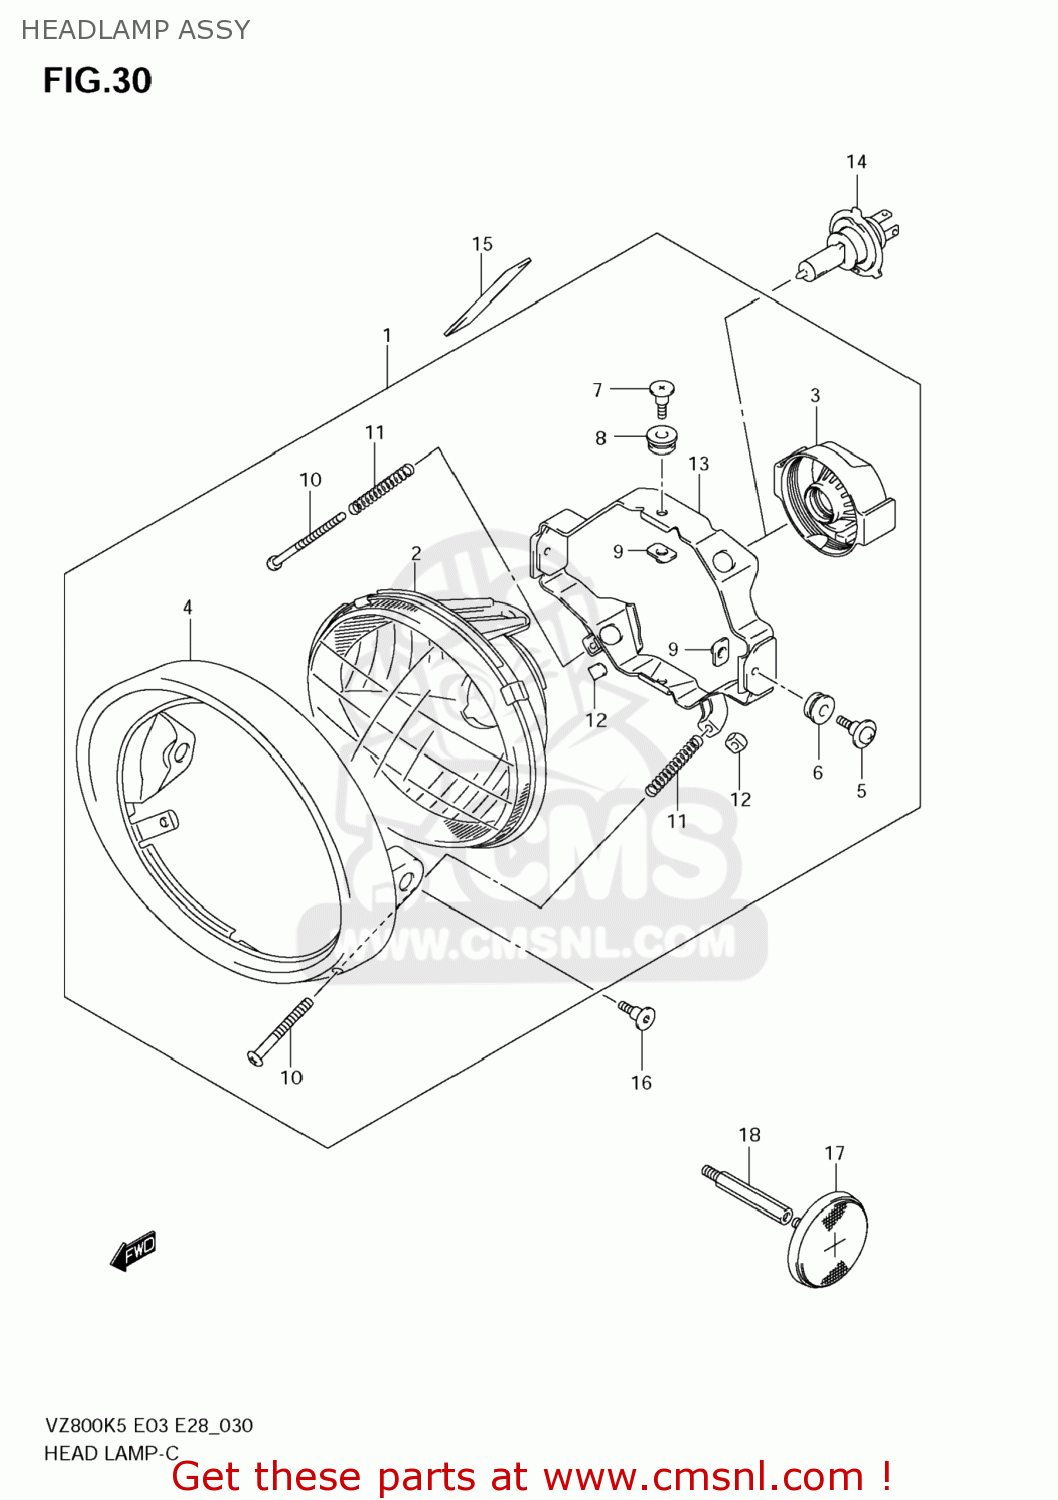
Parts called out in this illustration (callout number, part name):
1	HEADLAMP ASSY
2	UNIT
3	COVER
4	RIM
5	SCREW,MOUNTING
6	CUSHION
7	SCREW
8	CUSHION
9	NUT
10	SCREW,ADJUSTER
11	SPRING,ADJUSTER
12	NUT,HEADLAMP ADJUST
13	BRACKET
14	BULB(12V60/55W,H4)
15	PROTECTOR(20X90)X1.0
16	SCREW(5X12)
17	REFLECTOR,REFLEX
18	BOLT
